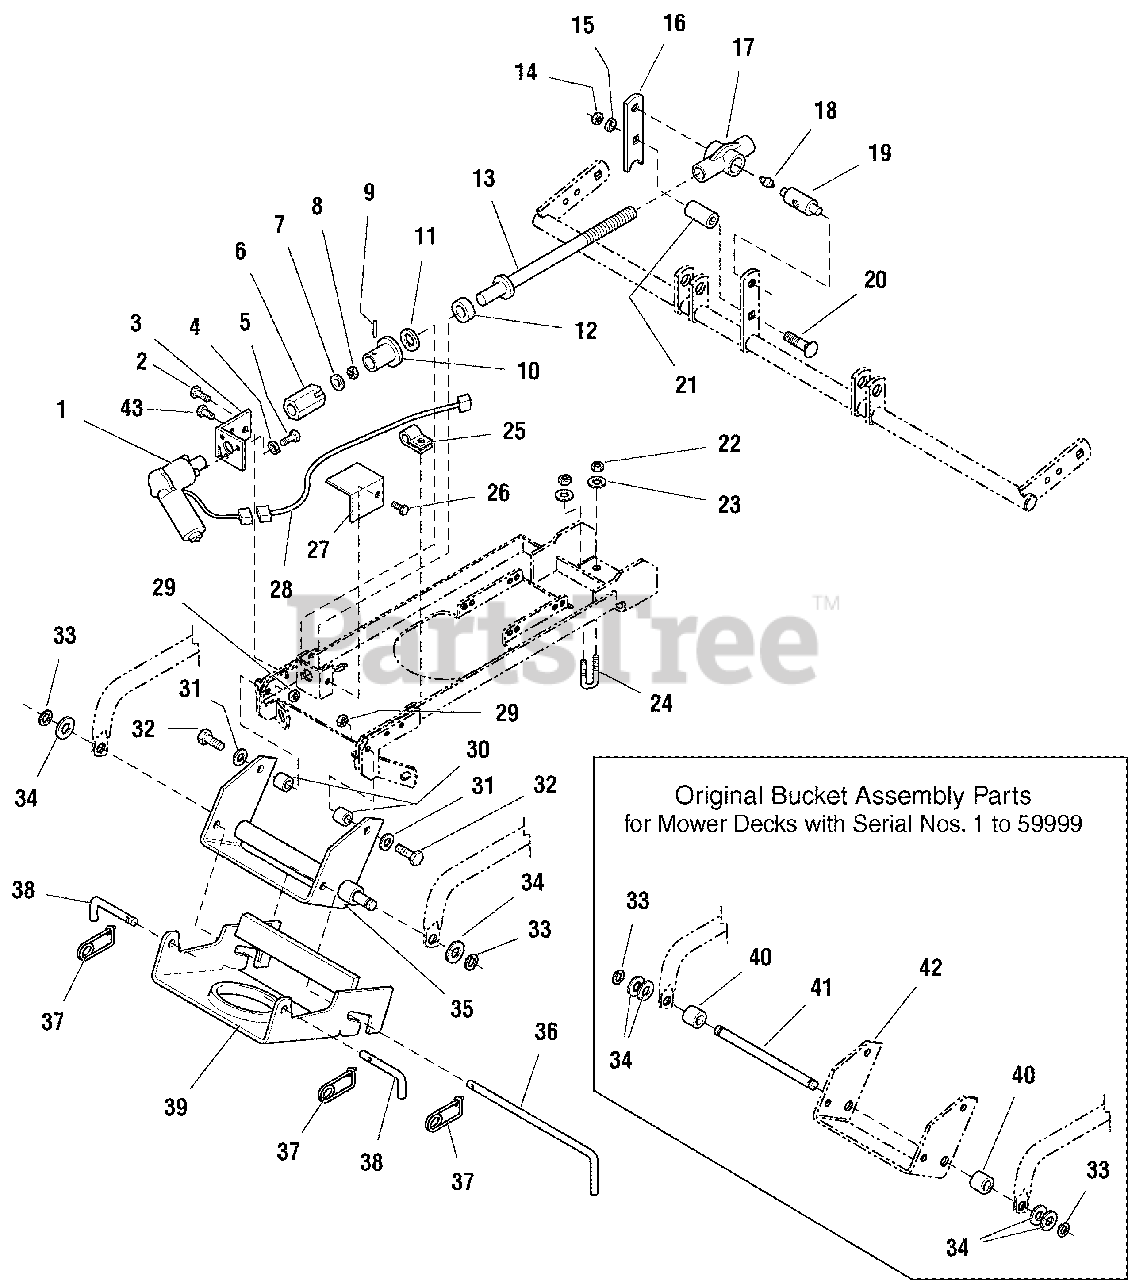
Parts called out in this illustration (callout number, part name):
1	MOTOR, Electric Cutting Height Adjust
2	CAPSCREW, Hex Washer Head, Taptitek, 5/16-18 x 1, Black
3	BRACKET, Motor Mounting
4	LOCKWASHER, 1/4
5	CAPSCREW, Hex Head, 1/4-20 x 3/4
6	ADAPTER, Motor
7	WASHER, Plain, 1/4
8	NUT, Hex Centerlock, 1/4-20
9	ROLL PIN, 3/16 x 1 3/4
11	WASHER, Nylon
12	BEARING, Thrust
13	SHAFT ASSEMBLY
14	NUT, Hex, 1/2-13
15	LOCKWASHER, 1/2
18	FITTING, Lube
20	CARRIAGE BOLT, 1/2-13 x 2 1/2
22	NUT, Hex Nylon Lock, 5/16-18
23	WASHER, Plain, 5/16
24	U-BOLT, Clamp
26	CAPSCREW, Hex Head, Taptite, 5/16-18 x 1/2
27	COVER
28	HARNESS, Mower lift
29	NUT, Hex Alm Insert Lock, 3/8-16
31	WASHER, Plain, 3/8
32	CAPSCREW, Hex Head, 3/8-16 x 1 1/2
33	RETAINING RING, 5/8
34	WASHER, 5/8
35	HITCH & SHAFT ASSEMBLY
37	PIN, Retainer
39	HITCH & BAR ASSEMBLY, Mower Front Hitch
41	SHAFT, Hitch
42	HITCH & SHAFT ASSEMBLY
43	CAPSCREW, Hex Washer Head, Taptite 5/16-18 x 3/4 Black
